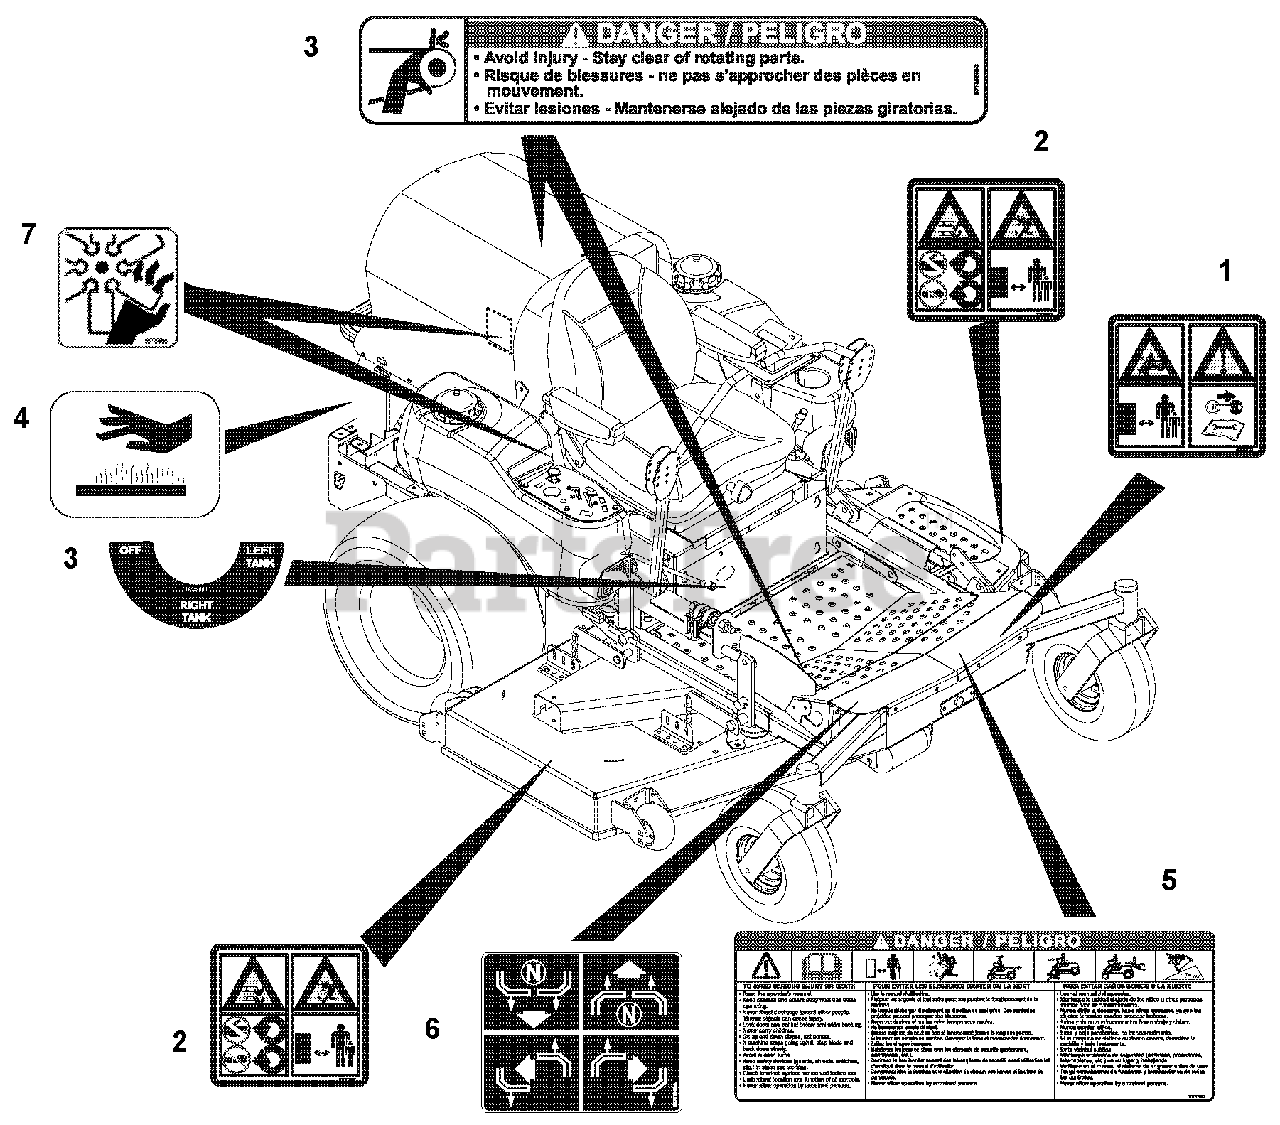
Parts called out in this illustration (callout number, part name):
1	Decal, CE Caution
2	Decal, CE Caution
3	Set, Decal-Common Danger/Fuel
4	Decal-Hot Surface
5	Decal, Warning
6	Decal-Instructional
7	Decal, Danger Fan
